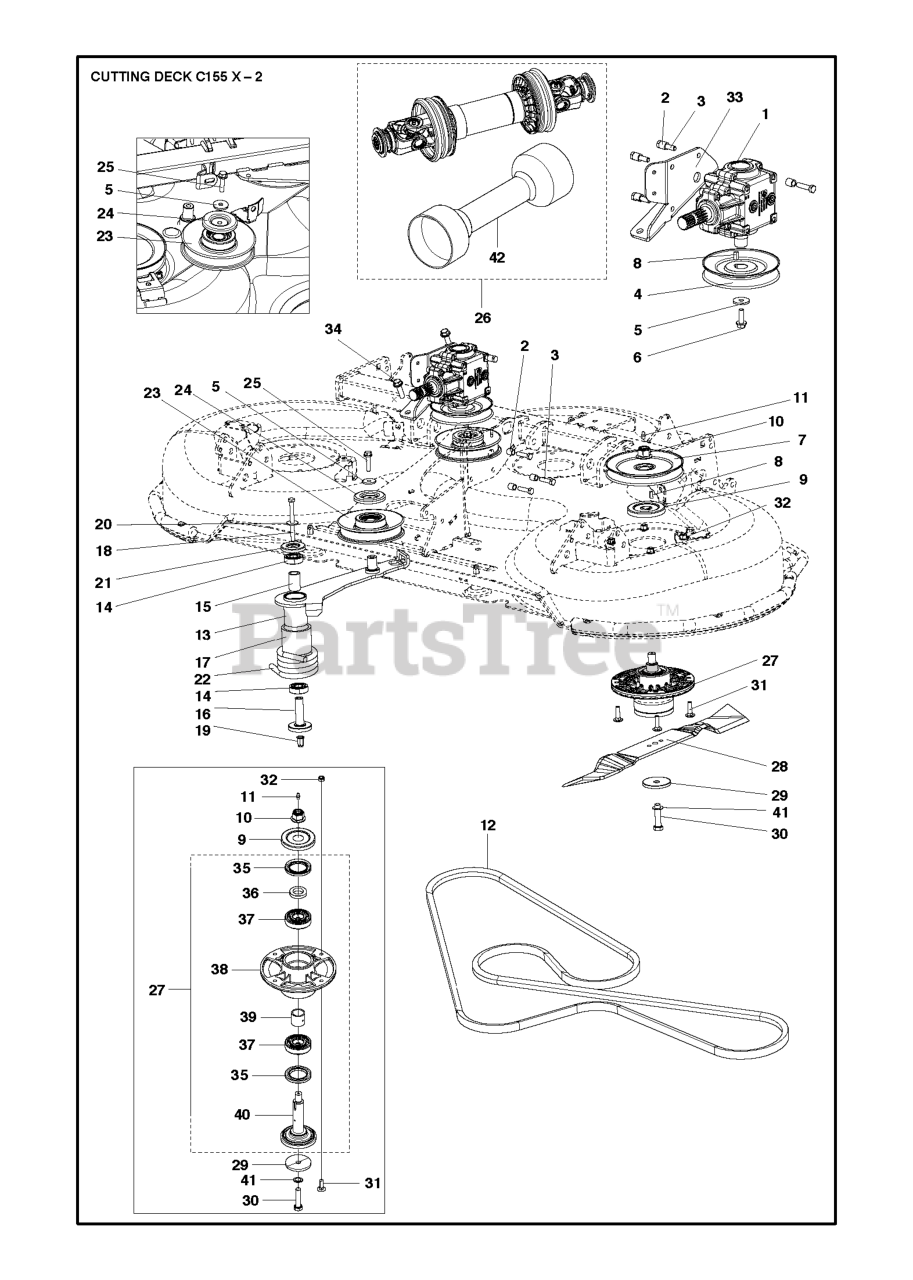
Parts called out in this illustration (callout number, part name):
11	GREASE NIPPLE
14	BALL BEARING
17	SPACER, IDLER PIVOT
19	BLIND RIVET NUT
21	DUST SHIELD
25	SCREW EHHFM
28	BLADE COMBICLIP 155 REAR DISCH
32	NUT FLANGE
37	BALL BEARING 6305 C3
41	SPRINGWASHER
